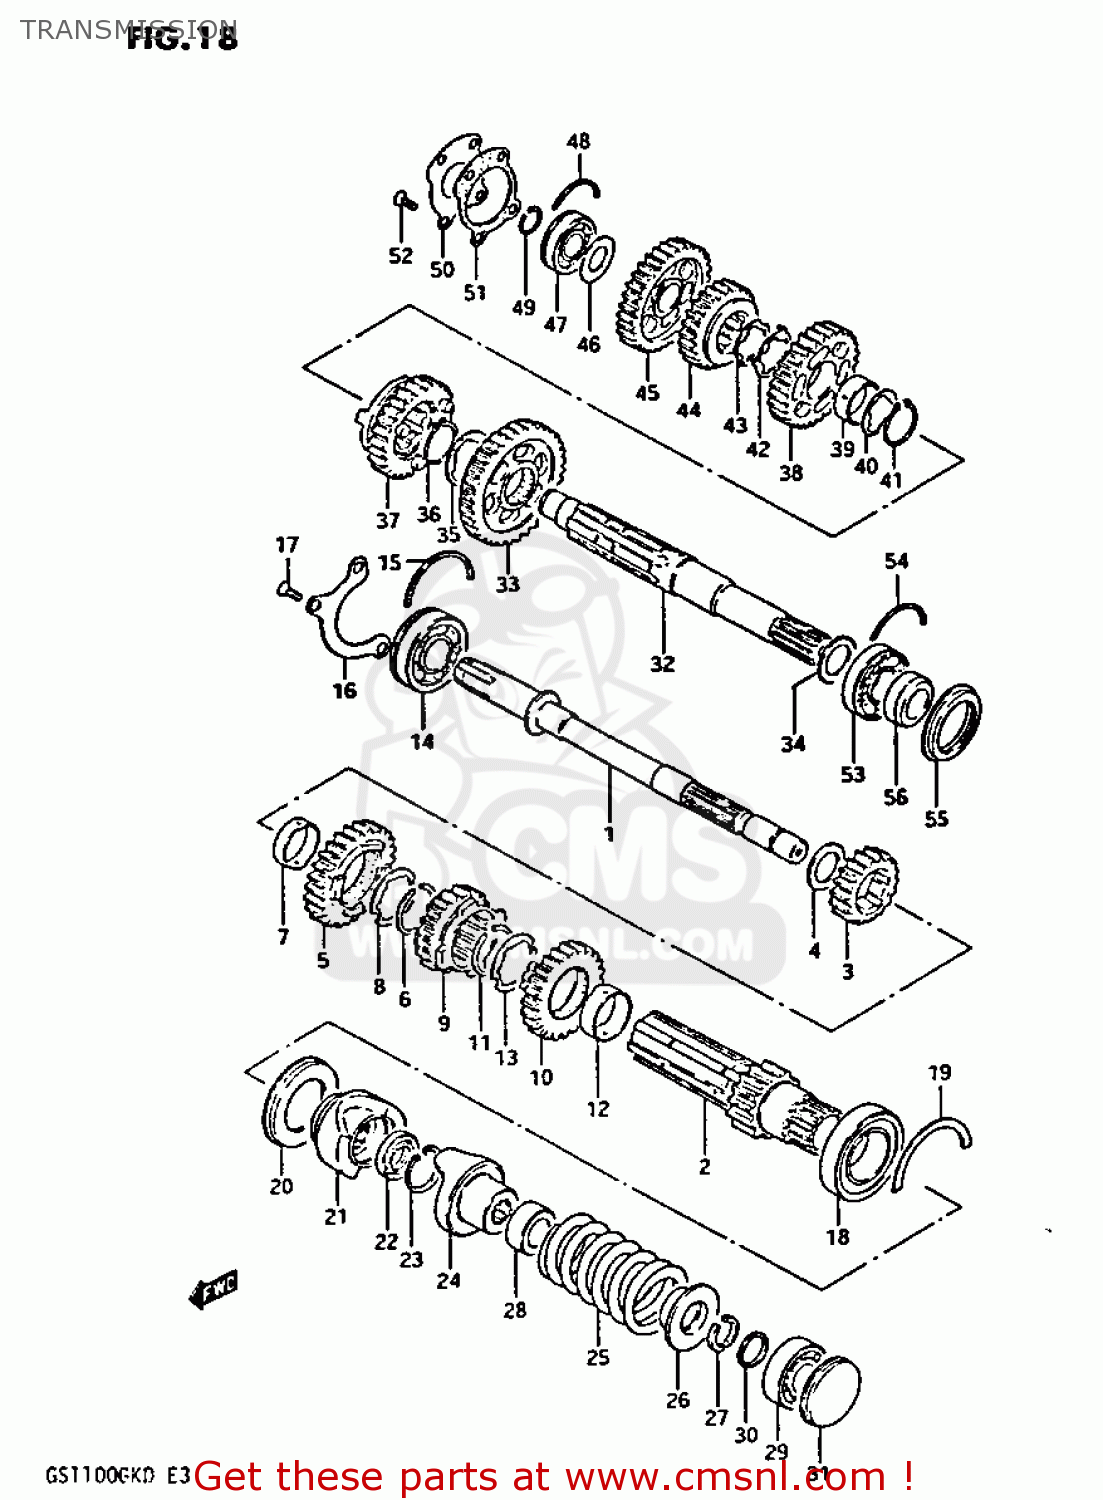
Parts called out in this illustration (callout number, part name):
1	SHAFT,INNER COUNTER
2	SHAFT,OUTER COUNTER
3	GEAR,SECOND DRIVE
4	WASHER (21X35X2)
5	GEAR,5TH DRIVE(NT:26)
6	RING,SNAP
7	SPACER,DRIVE GEAR
8	LOCK WASHER,5TH DR GEAR SPACER
9	GEAR,THIRD DRIVE
10	GEAR,FOURTH DRIVE
11	RING,SNAP
12	SPACER,DRIVE GEAR
13	LOCK WASHER,5TH DR GEAR SPACER
14	BEARING(25X62X17)
15	C-RING
16	RETAINER,CNTR SHAFT BEARING
17	SCREW
18	BALL BEARING 32X58X13
19	C-RING
20	SEAL,OIL(40X58X7)
21	DOG,OUTPUT CAM
22	SEAL,OIL(20.6X31X6)
23	CIRCLIP
24	DOG,INPUT CAM
25	SPRING
26	STOPPER,CAM DOG SLIDING
27	STOPPER,CAM DOG
28	GUIDE,CAM DOG SPRING
29	BEARING(17X40X12)
30	SPACER (17X21X3.5)
31	PLUG
32	SHAFT,DRIVE
33	GEAR,FIRST DRIVEN
34	WASHER, LH
35	WASHER,LOCK
36	CIRCLIP
37	GEAR,FOURTH DRIVEN
38	GEAR,3RD DRIVEN(NT:29)
39	BUSH,3RD DRIVEN GEAR
40	WASHER,LOCK
41	CIRCLIP
42	WASHER
43	WASHER,LOCK
44	GEAR,FIFTH DRIVEN
45	GEAR,SECOND DRIVEN
46	WASHER
47	BEARING(20X47X14)
48	C RING
49	CIRCLIP
50	PLATE,DRIVESHAFT
51	GASKET,DRIVESHAFT PLATE (MCA)
52	SCREW
53	BEARING
54	C RING
55	SEAL,OIL(35X52X6)
56	SPACER,DRIVESHAFT,LEFT
